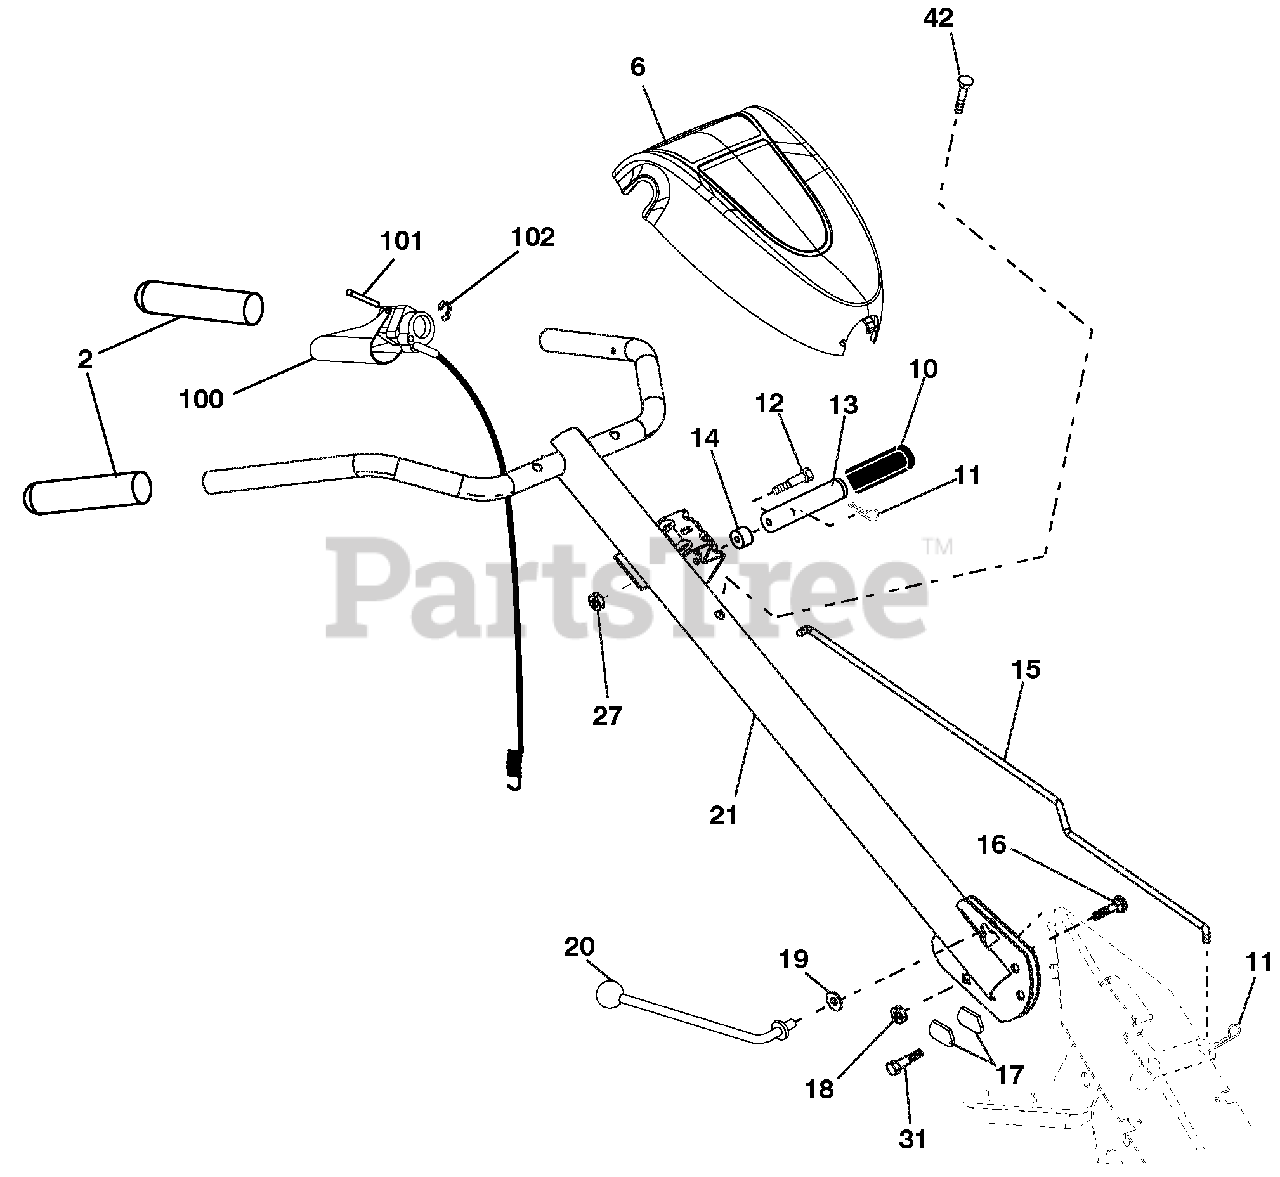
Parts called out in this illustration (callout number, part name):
2	GRIP, HANDLE
6	Console Control
10	Handle, Grip
11	Retainer Spring
12	Bolt, Shoulder
13	Handle, Shift
14	Grommet, Rubber
15	Rod, Shift
16	Bolt 3/8-16 x 1 Gr. 5
17	Lock, Handle
18	Nut, Hex Flange 1/4-20 unc
19	Washer 13/32 x 1 x 11 Ga.
20	Lever, Lock, Handle
21	Handle, Assemble
27	Nut, Hex, Crownlock 3/8-16
31	Bolt, Pivot
101	Pin, Pivot
102	Retaining Ring
